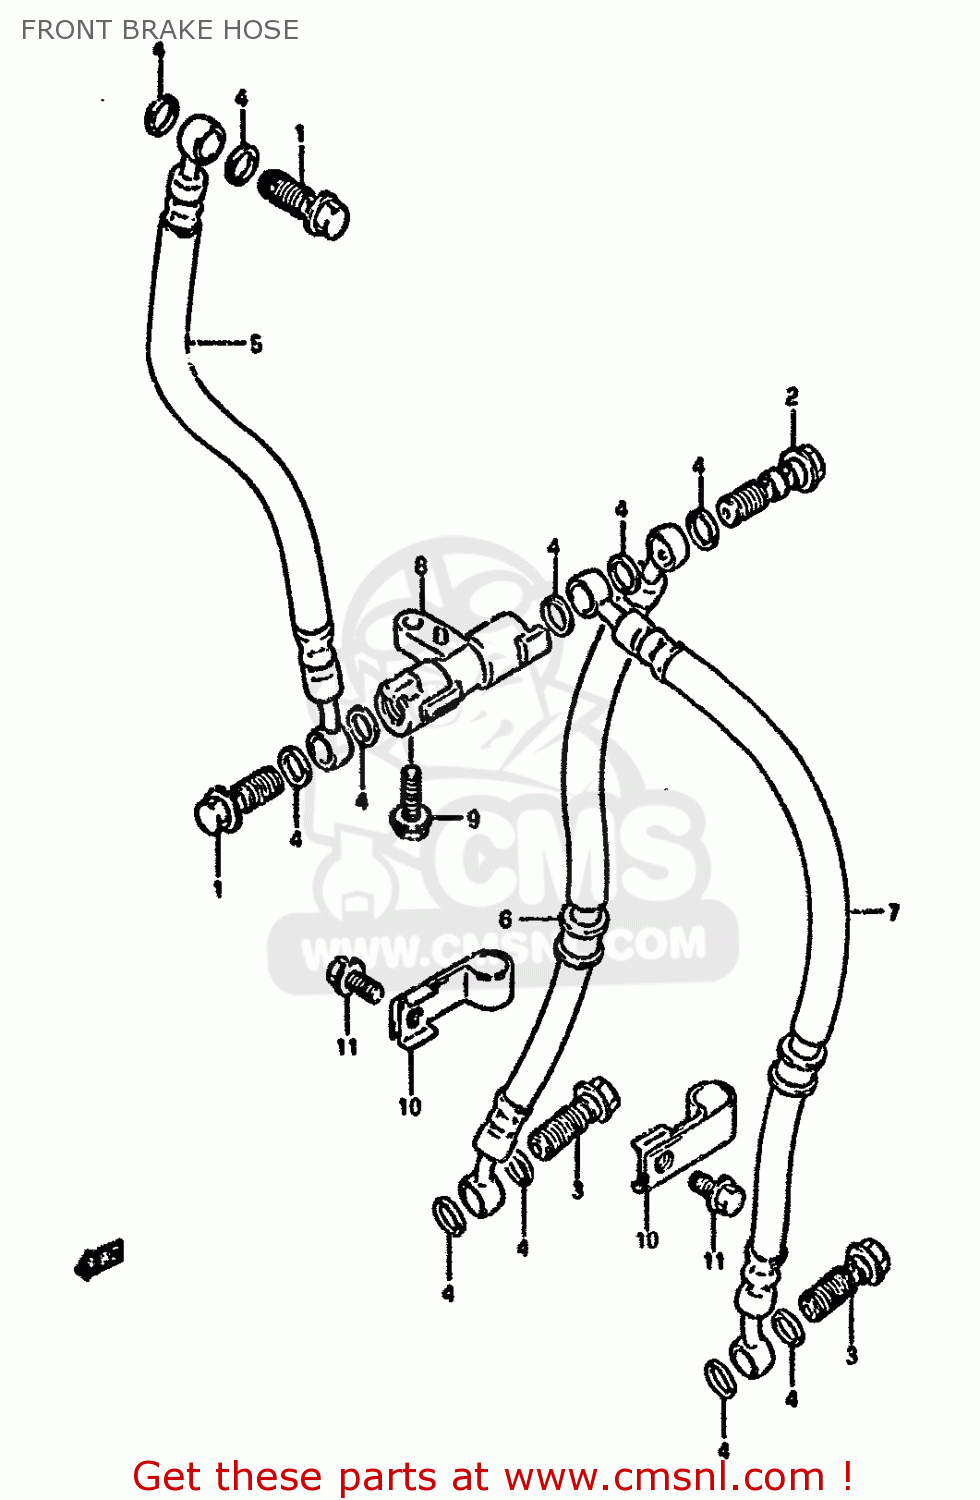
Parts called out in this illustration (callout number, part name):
1	BOLT UNION
2	BOLT UNION
3	BOLT UNION
4	WASHER(10X15X1.5)
5	HOSE COMP,FRONT BRAKE
6	HOSE,FRONT BRAKE,NO.2 RH
7	HOSE,FRONT BRAKE,NO.2 LH
8	JOINT,BRAKE HOSE
9	BOLT
10	CLAMP,FRONT BRAKE NO.2
11	BOLT
